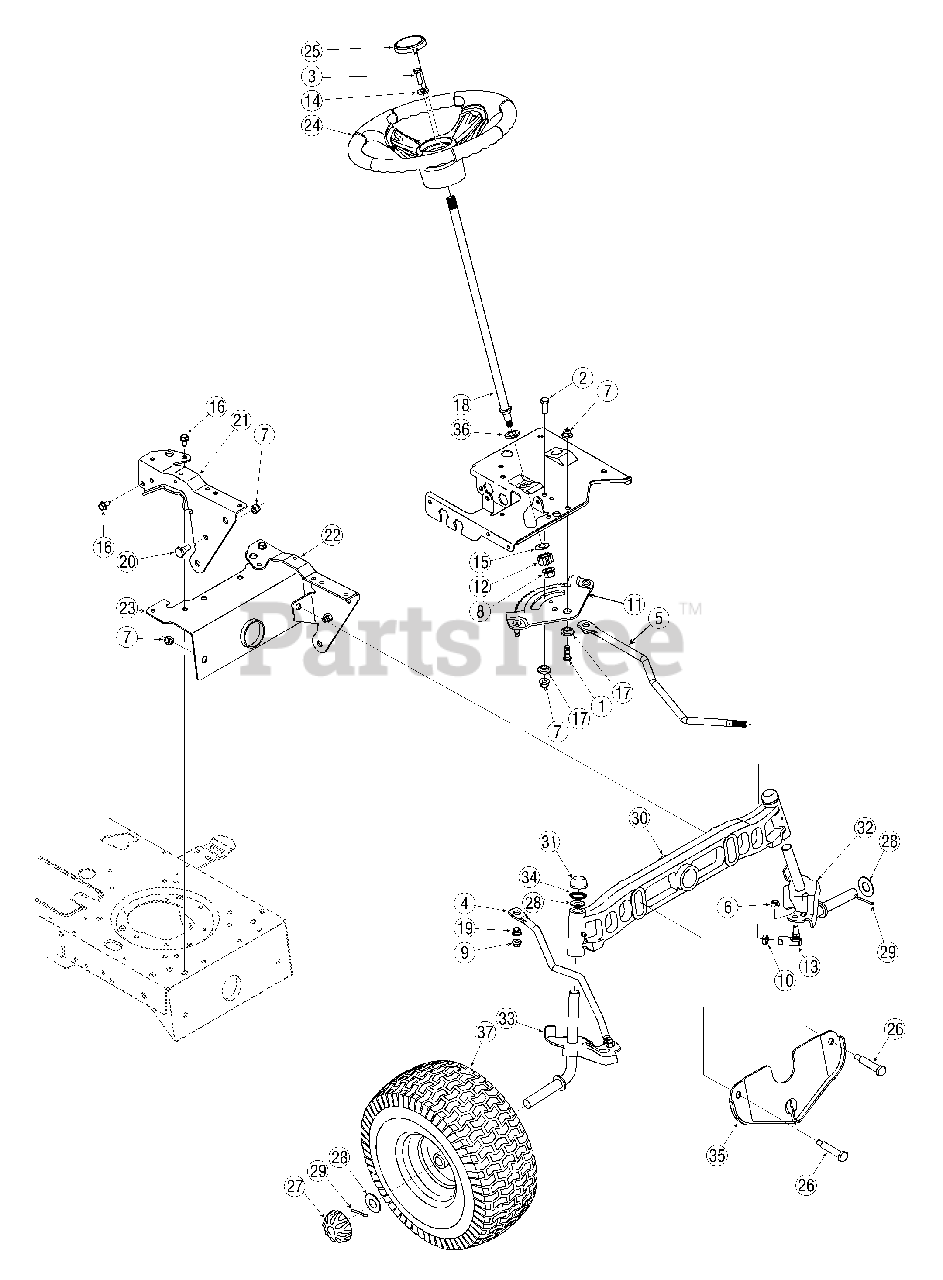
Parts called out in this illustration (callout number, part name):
1	Hex Screw, 3/8-16, 1.00, Gr5
2	Hex Screw, 3/8-16, 1.00, Gr5
3	Hex Screw, 5/16-18, 1.00, Gr5
4	Link, Drag, RH
5	Link, Drag, LH
6	Nut, Hex Lock, 3/8-24
7	Nut, Flange Lock, 3/8-16, Grf, Nylon
8	Nut, Flange Lock, 7/16-20
9	Nut, Flange Lock, 5/16-18, Gr5
10	Nut, Jam, 7/16-20, Gr2
11	Gear, Steering, 11/90 Ratio
12	Gear, Pinion, Steering
13	Ball Joint, 7/16-20, Lock
14	Washer, Flat,.406 x.875 x.105
15	Washer, Flat,.51 x 1.12 x.06
16	Screw, 5/16-12, 0.750
17	Spacer, Shoulder,.38 x 1.00 x.31
18	Shaft, Steering,.625 OD x 24.25 Lg
19	Plastic Bushing.380 ID
20	Screw, Shoulder,.498 x.340, 3/8-16
24	Steering Wheel, 3 Spoke, Soft Grip
24	Steering Wheel, 3 Spoke, Standard Grip
25	Steering Wheel Cap
26	Shoulder Screw,.5 x 2.380, 3/8-16
27	Deluxe Hub Cap
28	Flat Washer,.78 x 1.589 x.06
29	Cotter Pin, 5/32 x 1.25
30	Pivot Bar, Cast Iron
32	LH Axle Assembly,.750
33	RH Axle Assembly,.750
36	Hex Flange Bearing
37	Wheel Assembly Complete, 15 x 6
